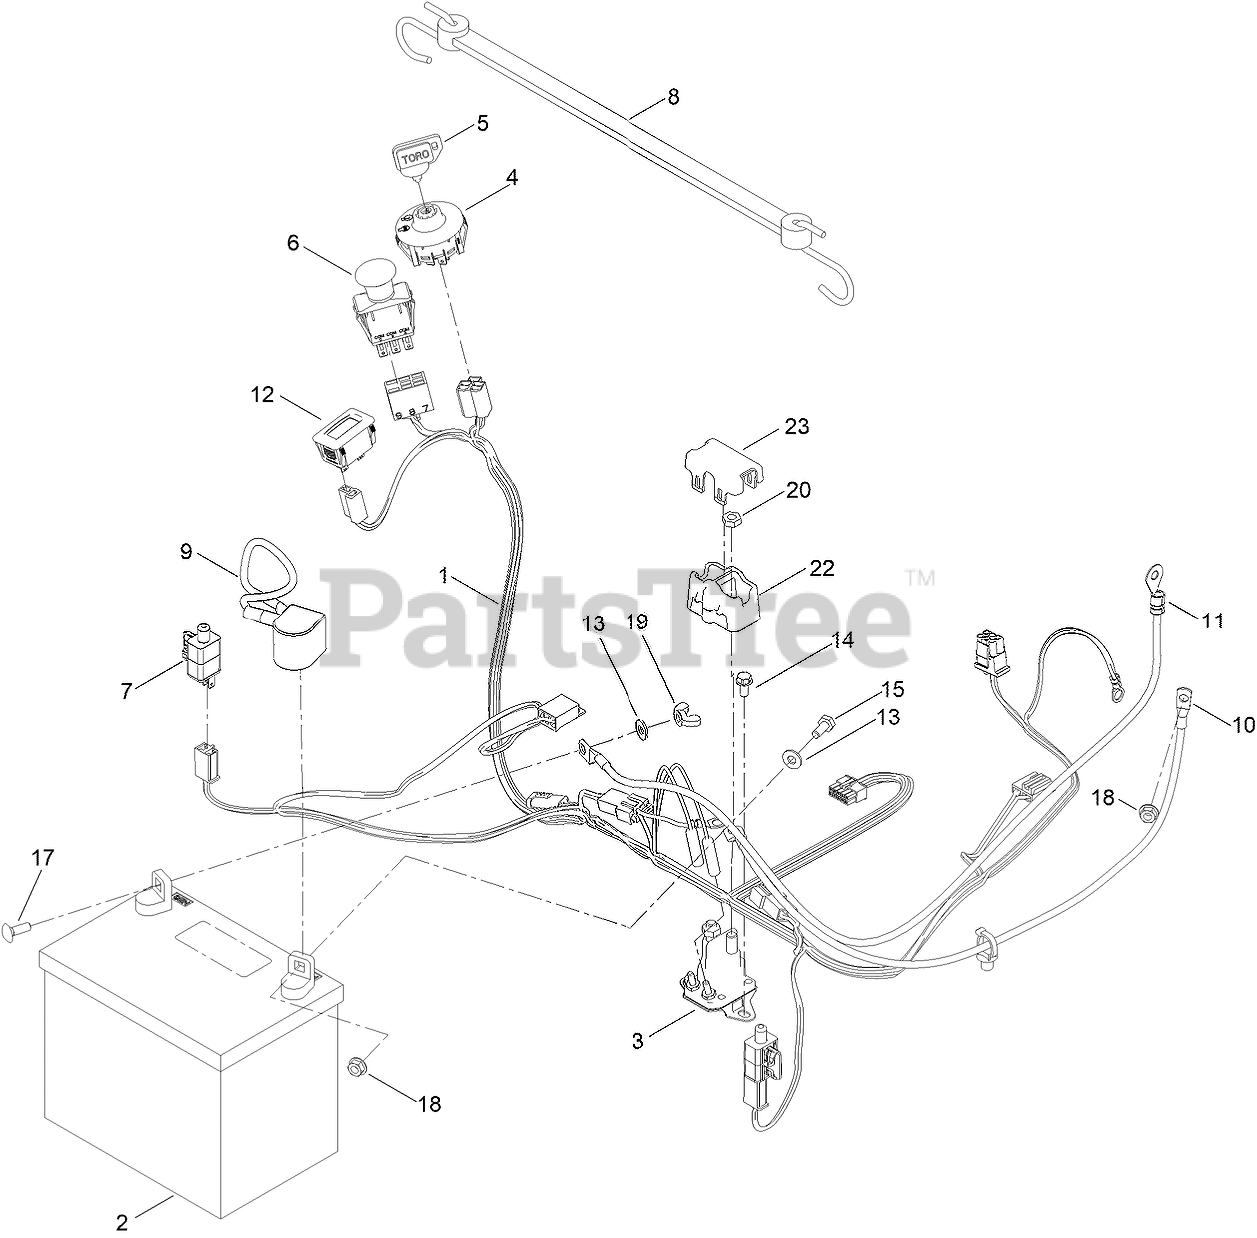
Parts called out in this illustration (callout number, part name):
1	HARNESS-WIRE
2	BATTERY
3	SOLENOID
4	SWITCH-IGNITION
5	KEY-IGNITION
6	SWITCH-PTO
7	SWITCH
8	STRAP-RUBBER
9	CABLE-BATTERY, POS
10	CABLE-BATTERY, RED (8 GAUGE)
11	CABLE-BATTERY, BLACK
12	HOURMETER
13	WASHER-FLAT
14	SCREW-HWH
15	SCREW-HH
17	BOLT-CARR
18	NUT-HF
19	NUT-WING
20	NUT-JAM
22	COVER-SOLENOID
23	CAP-SOLENOID
